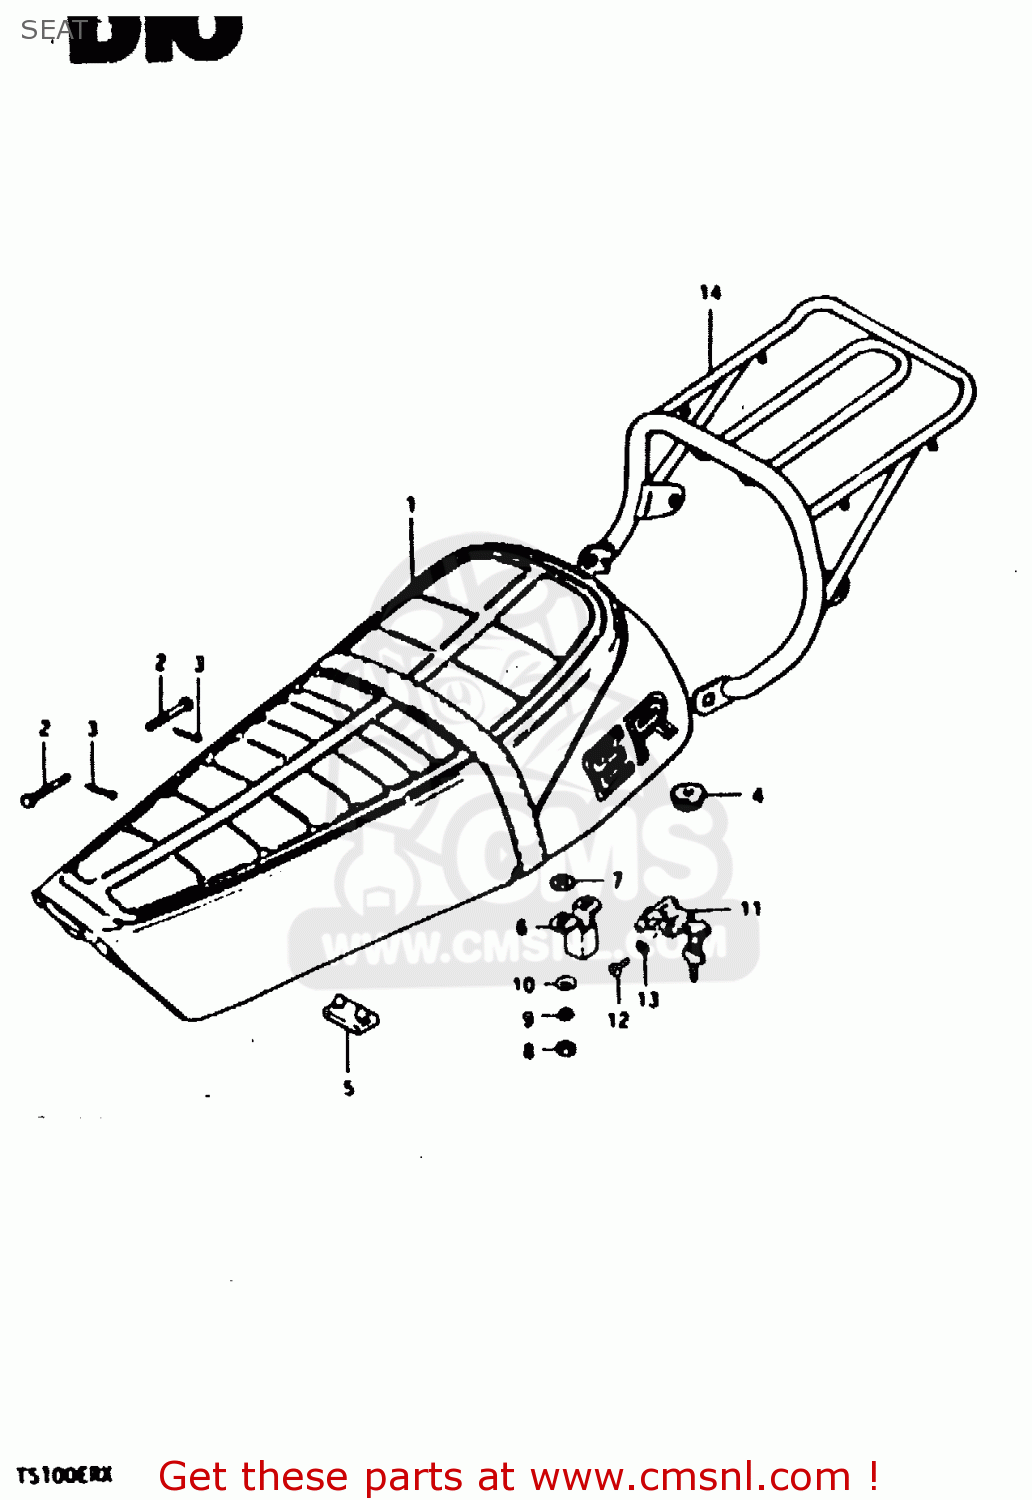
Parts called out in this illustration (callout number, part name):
1	SEAT ASSY (BLACK)
2	PIN
3	PIN
4	CUSHION
5	CUSHION
6	PLATE,CLAMP GUIDE
7	WASHER(8.5X18X1)
8	NUT
9	LOCK WASHER
10	WASHER
11	LOCK ASSY,SEAT
12	SCREW
13	LOCK WASHER
14	CARRIER,SPORT
